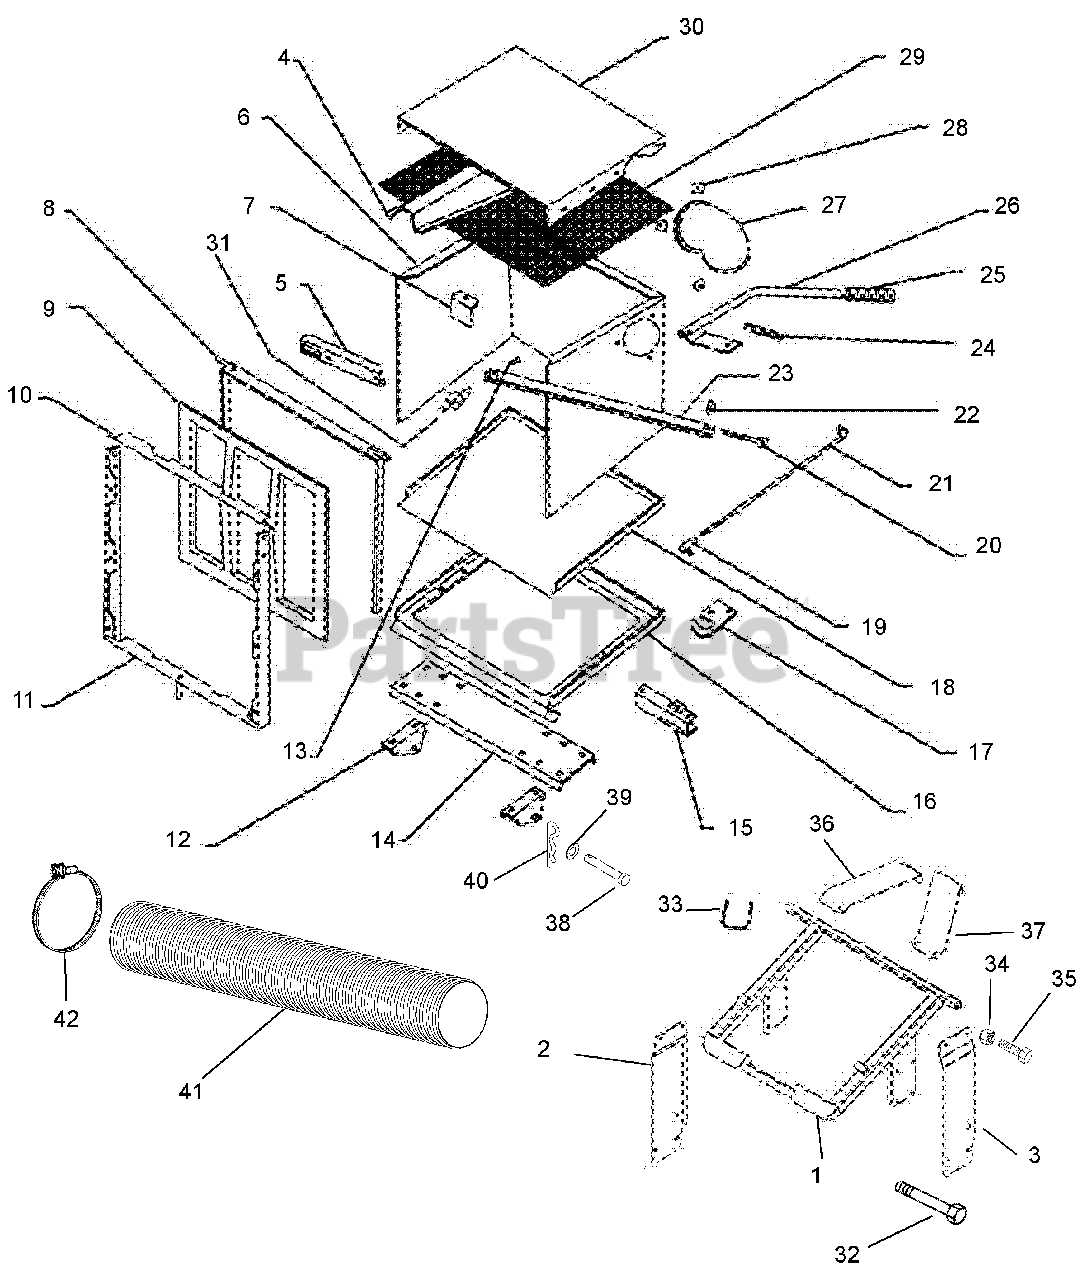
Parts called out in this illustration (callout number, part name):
1	Frame, Main
2	Frame, Main Left Leg
3	Frame, Main Right Leg
4	Screen Support
5	Handle Mount
6	Box Back and Sides
7	Fill Gauge
8	Box Door/Frame
9	Plastic Door
10	Upper Door Member
11	Door Frame Assembly
12	Pivot Bracket
13	Linkage Pin
14	Base Frame Pivot Mount
15	Latch Hook Plate
16	Base Frame
17	Latch Hook
18	Box Bottom
19	Ball Joint
20	Adjusting Screw
21	Latch Rod
22	Nut, Adjusting
23	Rod, Linkage
24	Spring, Latch
25	Grip, Handle
26	Handle, Box
28	Clamp, Inlet
30	Box Top, Aluminum
31	Rue-Lock Pins
32	Bolt, Hex ..38-16 x 2.75
33	U-Bolt, ROPS Mounting
34	Nut, Nylon Lock .375-16
35	Bolt, Hex .38-16 x 1.00
36	Bracket, LH ROPS Support
37	Bracket, RH ROPS Support
38	Pin, Detent .625 x 3.00
39	Washer Flat Steel .656 x 1.31 .095
40	Pin, Hair .156 x 2.625
41	Hose, 7 x 63" Kanaflex 165CL
42	Clamp, Tool-Less Hose
